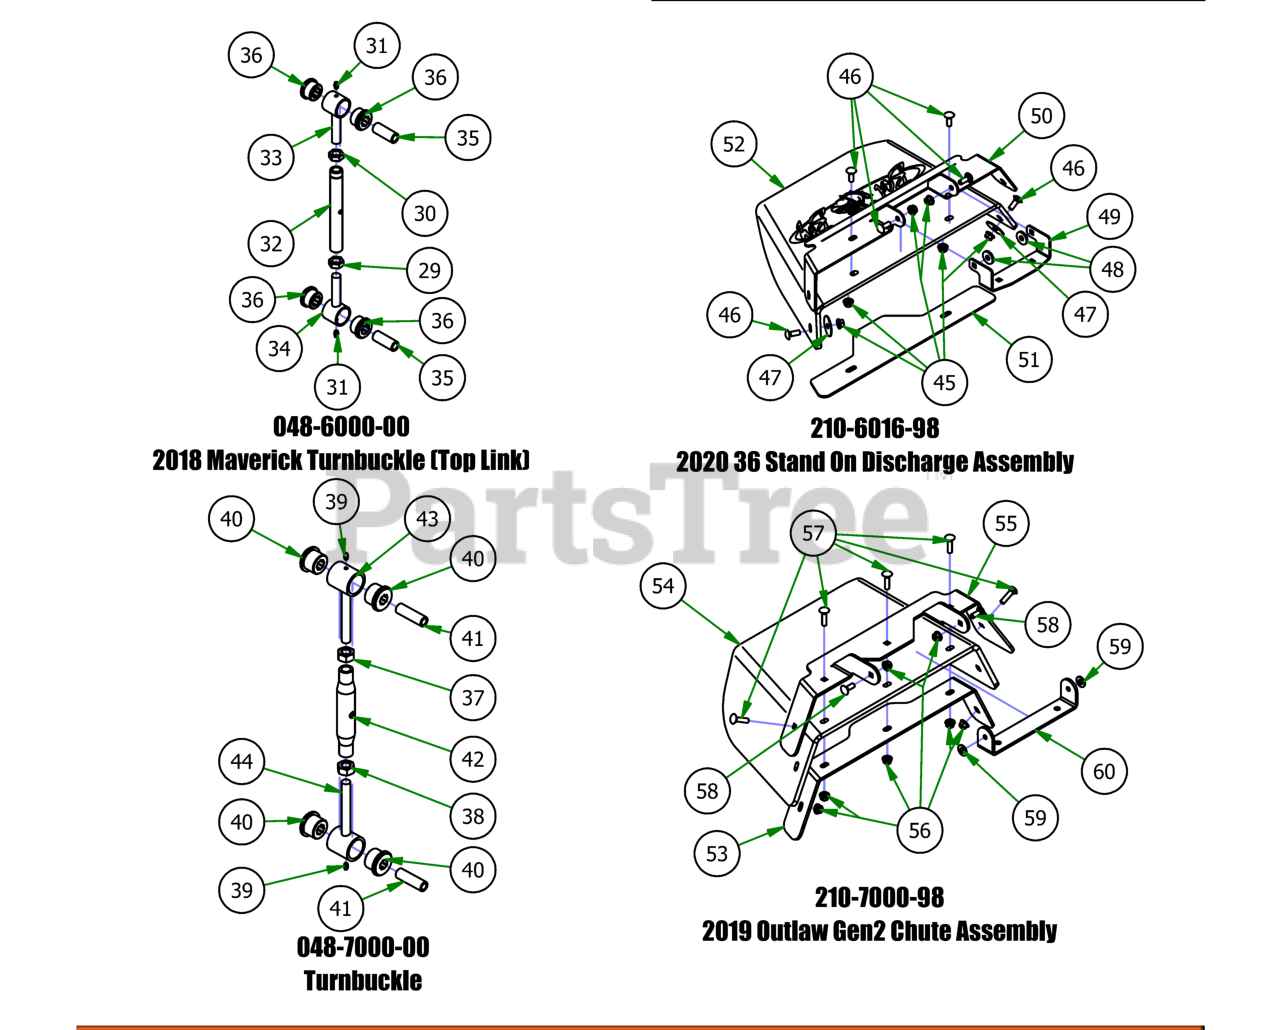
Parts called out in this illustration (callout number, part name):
29	NUT, 5/8-18
30	NUT, 5/8-18LH
31	1/4-28 Grease Fitting
32	2018 Maverick Toplink Body
33	2018 Maverick Bushing Retainer Left-Handed
34	2018 Maverick Bushing Retainer Right-Handed
35	2018 Maverick Bushing Sleeve
36	2018 Maverick Bushing
37	Hex Nut, 11/16-12
38	Hex Nut, 11/16-12 Left Handed
39	1/4" Press in Grease Fitting
40	Polyeurethane Bushing
42	2015 Outlaw Toplink Body
43	2015 Outlaw Toplink RH End
44	2015 Outlaw Toplink LH End
45	5/16-18 NYLON INSERT FLANGE LOCKNUT ZINC
46	5/16-18 X 7/8 CARRIAGE BOLT ZINC
47	5/16 FENDER WASHER (1-1/2 OD) ZINC
48	.360 ID X .983 OD X .120 THICK FLAT WASHER NYLON
49	2020 36 Stand On Chute Hanger
50	Discharge Chute Bracket 48 MZ (Upper)
51	2017 MZ Discharge Chute Bracket-Lower
52	Rubber Discharge Chute MZ (Component)
53	2019 Lower Chute Bracket
54	2019 Belted Chute with Logo
55	2019 Upper Chute Bracket
56	5/16" Nylon Flange Nut
57	5/16" x 1 1/4" Carriage Bolt
58	5/16" x 7/8" Carriage Bolt
59	.360 ID Plastic Washer
60	2019 Chute Hanger
